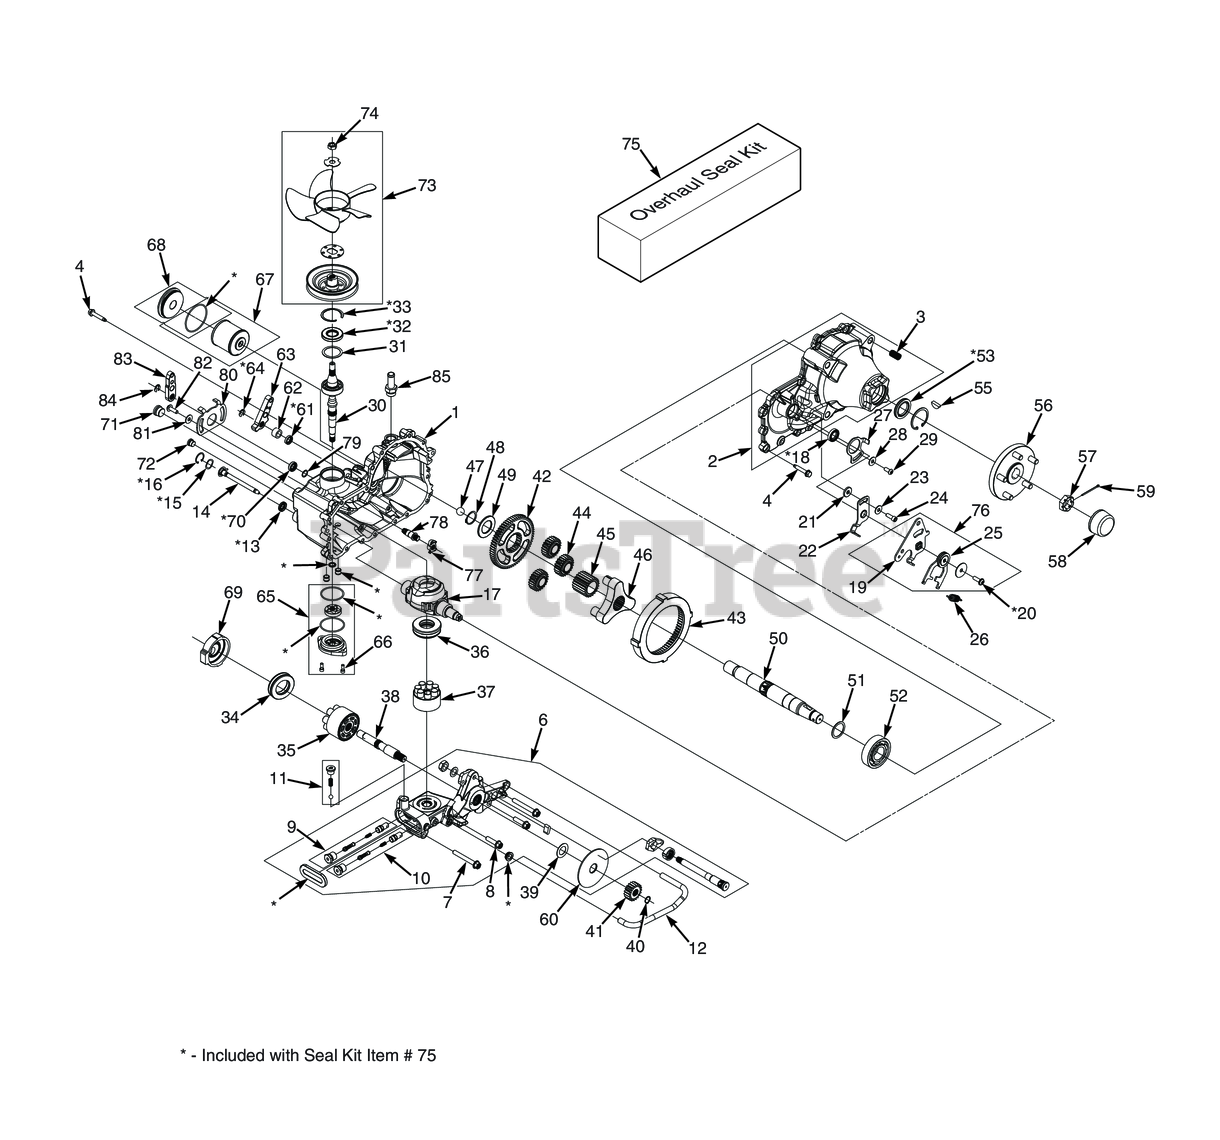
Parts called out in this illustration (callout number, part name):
1	Kit, Housing Main, LH
1	Kit, Housing Main, RH
2	Kit, Housing Side, LH
3	Insert, 1/2-13 x 1-1/2" UNC
4	Screw, Hex Flange 5/16-18 x 1-1/2"
5	Tube, Sealant
6	Kit, Center Section, LH
6	Kit, Center Section, RH
7	Bolt, Hex Flange 3/8-16 x 3"
8	Screw, Hex Flange Head 3/8-16 x 1-1/2"
9	Kit, Shock Valve
10	Kit, Shock Valve
11	Kit, Charge Relief
12	Tube, Filter, LH
12	Tube, Filter, RH
13	Seal, Lip 12x 24 x 5 TC
14	Kit, Bypass Actuator
15	Spring, Wave
16	Ring, Retaining, HO-100
17	Swash Plate, 16cc. Machined
18	Seal, Lip 22 x 32 x 7
19	Arm, Control, LH
19	Arm, Control, RH
20	Bolt, Hex Head Cap Screw 5/16-24 x 1" Patch
21	Spacer, .320 x 1.005 x .179
22	Arm, Neutral (Left Side)
22	Arm, Neutral (Right Side)
23	Washer, 7/16 x 7/8 OD x .06 HT
24	Bolt, Hex Head Cap Screw 5/16-24 x 1" Patch
25	Assembly, RTN Uni-Directional (CCW) LH
25	Assembly, RTN Uni-Directional (CW) RH
26	Spring, Extension, RTN - 44lbs
27	Plate, Stop, LH
27	Plate, Stop, RH
28	Washer, 7/16 x 7/8 OD x .06 HT
29	HBHCS, 5/16-18 x 3/4"
30	Kit, Input Shaft
31	Spacer
32	Seal, Lip 25 x 52 x 7 TC
33	Ring, Retaining Internal
34	Bearing, Thrust 42 x 68 x 16
35	Kit, Cylinder Block - 21cc.
36	Bearing, Thrust 35 x 70 x 22
37	Kit, Cylinder Block - 16cc.
38	Shaft, Motor
39	Washer, .89 x 1.50 x .04
40	Ring, Retaining .625
41	Gear, 19T
42	Gear, 65T
43	Gear, Ring 68T
44	Gear, Planet 23T
45	Gear, Sun 22T
46	Carrier
47	Ball, Thrust .75
48	Ring, Retaining 1-1/4"
49	Spacer, Thrust, Axle
50	Shaft, Axle
51	Washer, 1.40 x 1.75 x .05
52	Bearing, Ball 35 x 80 x 21
53	Seal, Lip 1.375 x 2.062 x .250
54	R i n g , Retaining 2.06 Internal
55	Key, Shaft, Axle
56	Kit, Hub, 5-Bolt
57	Nut, Hex 1-20 Slotted
58	Cap, Axle
59	Pin, Cotter 9/64 x 2"
60	Rotor, Brake
61	Seal, .56 x .88 x .19
62	Spacer, .57 x .86 x .53
63	Handle, Actuating
64	Ring, Retaining External .375"
65	Kit, Charge Cover
66	Screw, 1/4-20 x .625
67	Kit, Filter
68	Kit, Filter Plug
69	Plate, Motor Swash
70	Lip Seal (15 x 24 x 7)
71	Plug, 7/8-14
72	Straight Thread Plug
73	Kit, Fan / Pulley
74	Fan Nut (order through Hydro-Gear)
75	Seal Kit
76	Kit, RTN Bi-Directional LH
76	Kit, RTN Bi-Directional RH
77	Cam, 2-Speed
78	Shaft, 2-Speed, Bevel
79	Ring, Retaining External .59"
80	Arm, Lock Down 2-Speed
81	Washer, 7/16 x 7/8 OD x .06 HT
82	HBHCS, 5/16-18 x 3/4"
83	Handle, Actuating
84	Ring, Retaining External .375"
85	Fitting, 7/8-14 SAE, .625 Beaded
